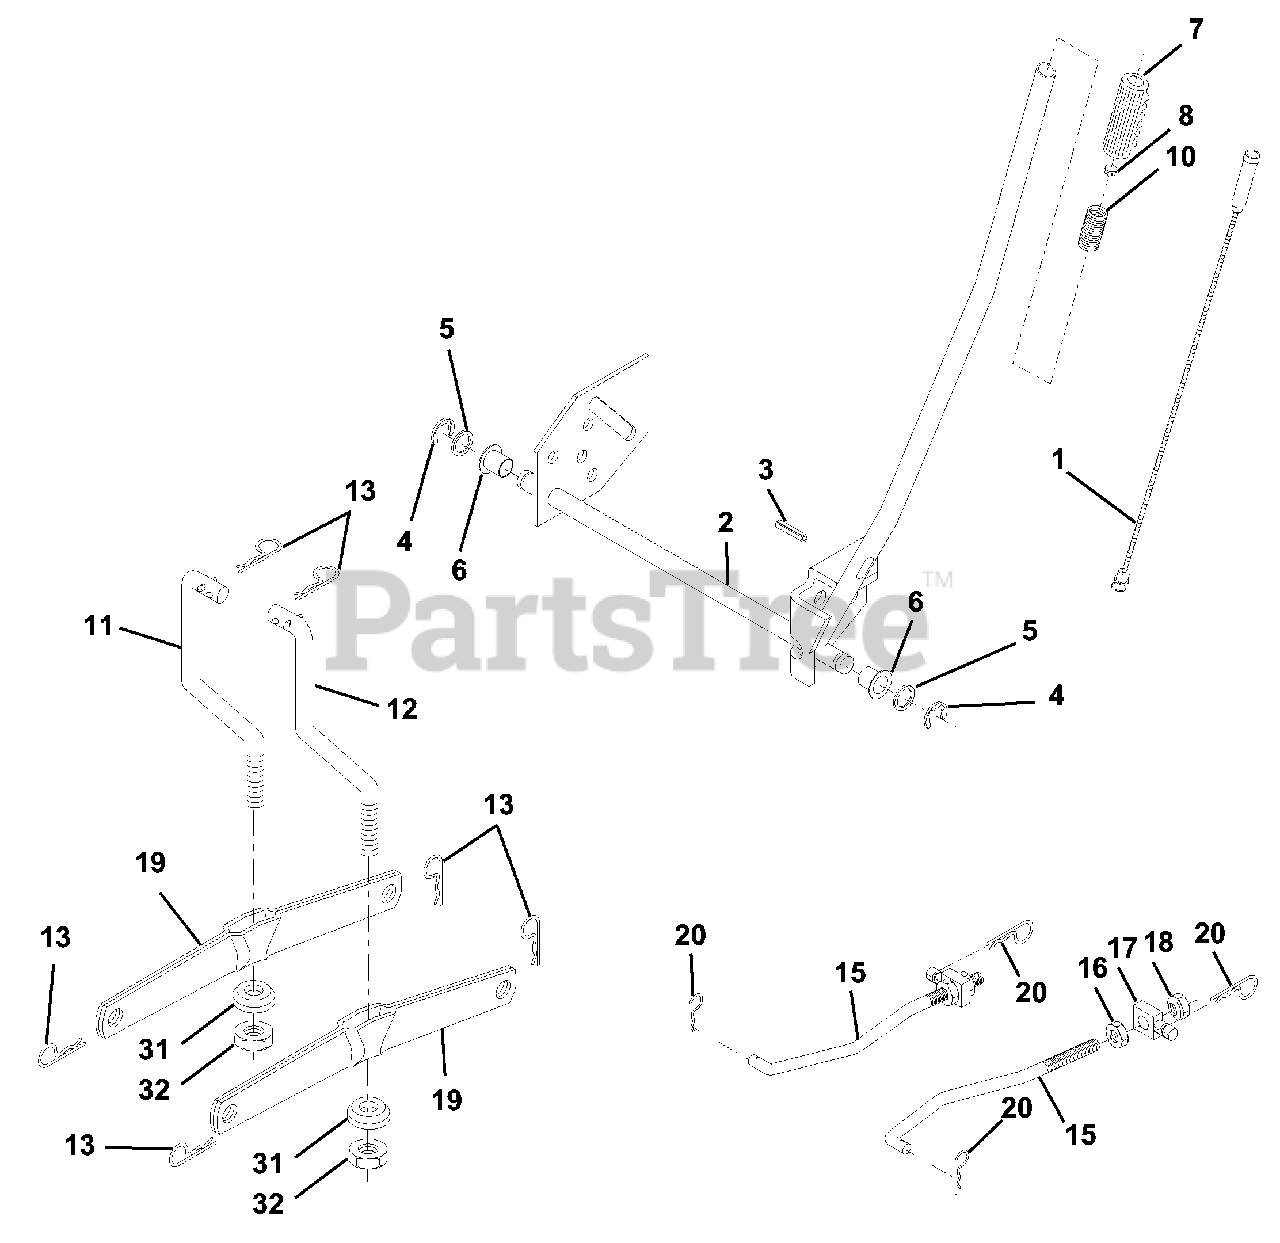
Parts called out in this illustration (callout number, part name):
1	Wire Asm Inner W/plunger 17 32
2	Shaft Asm Lift
3	Pin Groove
4	E Ring #5133-62
5	Washer PLTD 21/32 X 1 X 21ga
6	Bearing Nylon Blk 629 Id
7	Grip Handle Bicycle
8	Button Plunger Black
10	Spring Cprsn 3 750 Oiled
11	Link Lift LH
12	Link Lift RH
13	Retainer Spring
15	Link Front
16	Nut Jam Hex 1/2-13 Unc
17	Trunnion Blk Zinc
18	Nut Lock W/wsh 1/2-13unc
19	Arm Suspension Rear
20	Spring, Retainer
31	Bearing Pvt. Lift Spherical
32	Nut Crownlock 3/8-24
